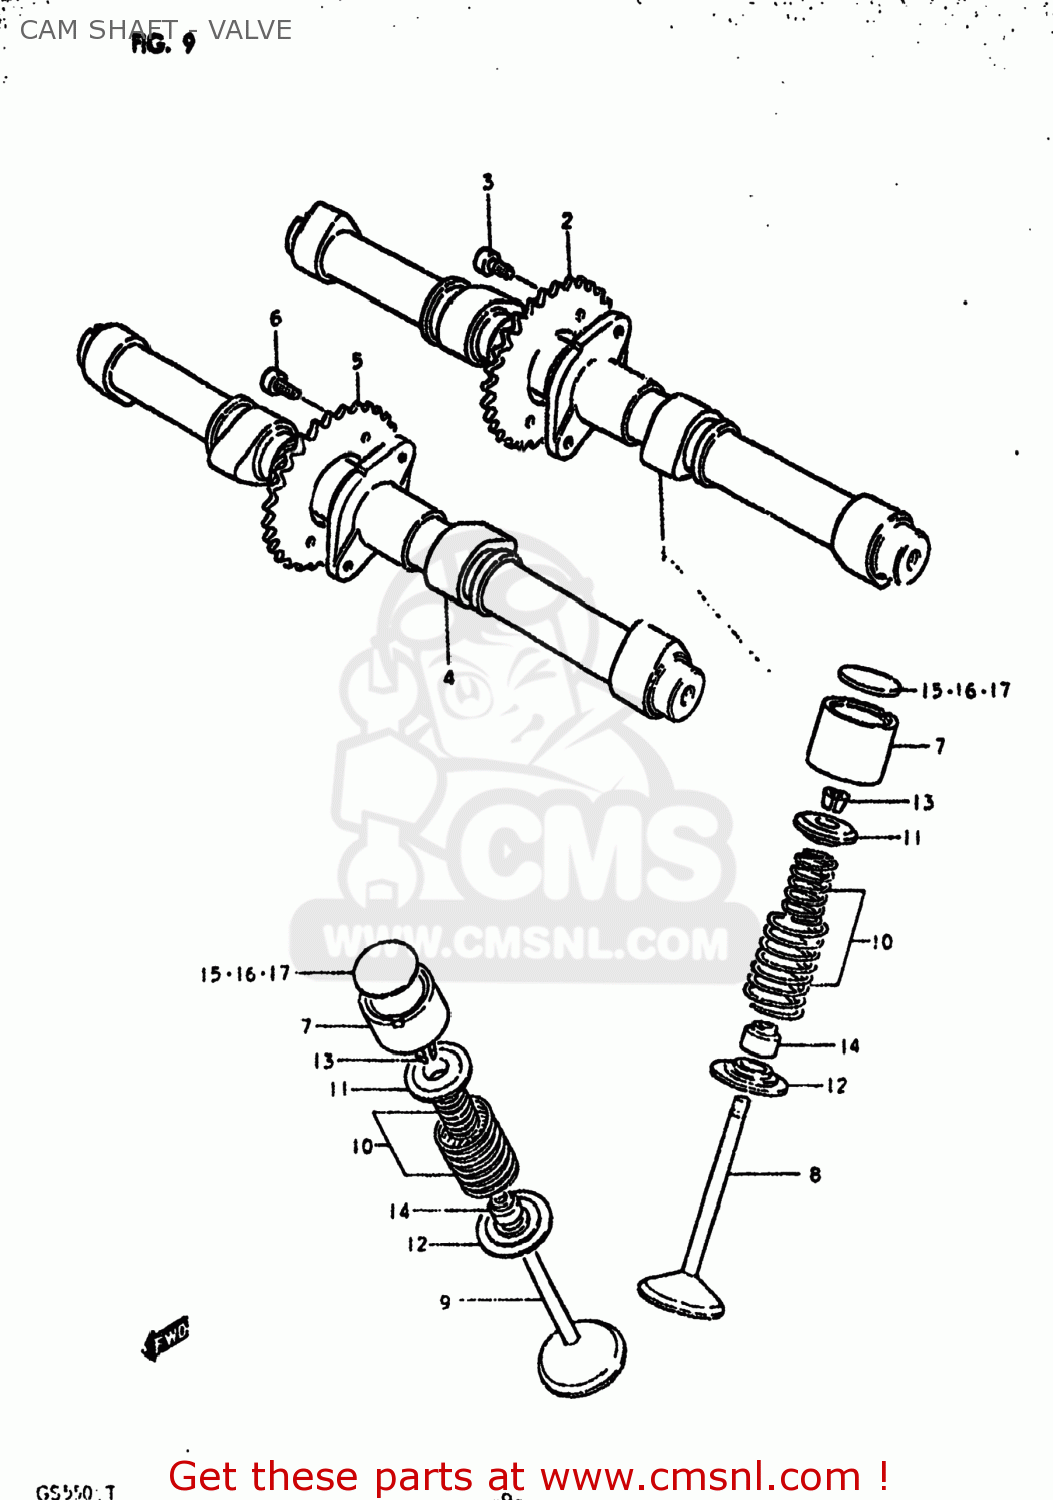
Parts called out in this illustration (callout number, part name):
1	CAMSHAFT
2	SPROCKET,CAMSHAFT
3	BOLT 6X11
4	CAMSHAFT,EXHAUST
5	SPROCKET,EXHAUST CAMSHAFT
6	BOLT 6X11
7	TAPPET
8	VALVE,INTAKE
9	VALVE,EXHAUST
10	SPRING SET,VALVE
11	RETAINER,VALVE SPRING
12	SEAT,VALVE SPRING
13	COTTER VALVE
14	SEAL,OIL(7X14.4X9)
15	SHIM,TAPPET
16	SHIM,TAPPET
17	SHIM,TAPPET
18	SHIM SET,TAPPET
19	CASE
